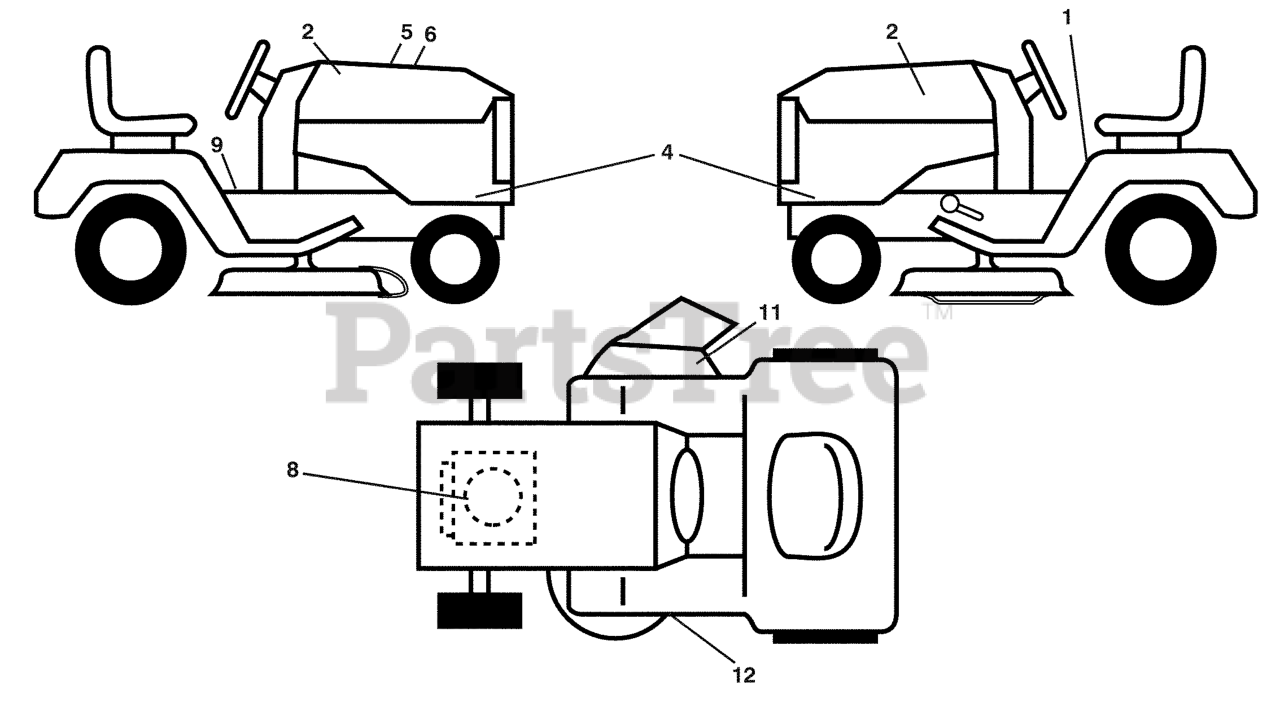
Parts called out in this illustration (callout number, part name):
1	DECAL.FENDER.WARNING.ENG
2	DECAL.HOOD.LOGO.ORANGE.HUSQVAR
4	DECAL.SIDE.PANEL.LTH2042/B&S
5	DECAL.WARNING.CUST.RESP.E85.
8	DECAL.ENG.BSM33.20INTK.27776
9	DECAL BTRY SYMBOLS
11	DECAL.WARN.KEEP.HAND.AWAY
12	DECAL V BELT SCHEMATIC
